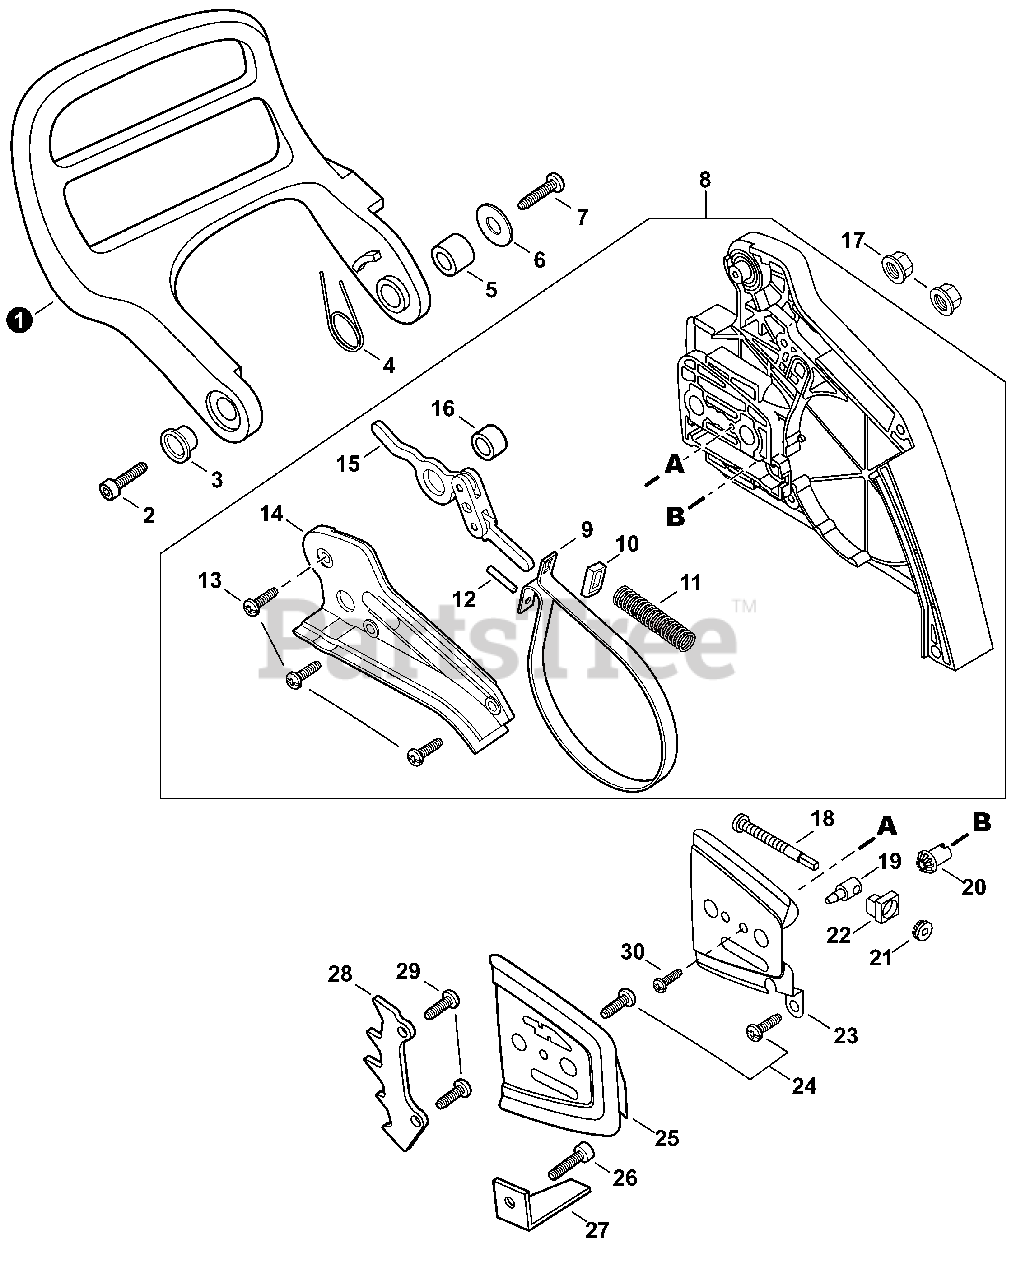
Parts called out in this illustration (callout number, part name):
1	LEVER, BRAKE
2	BOLT 5×16
3	COLLAR 10
4	SPRING, TORSION
5	SPACER 8×12×9
6	WASHER 4.2×16.5×1
8	BRAKE ASSY, CHAIN
9	BAND, BRAKE
11	SPRING, COMPRESSION
12	PIN, SPRING 3x-9.8
13	SCREW 4×12
14	COVER, BRAKE
15	CONNECTOR, BRAKE
16	SPACER 8×12×9
17	NUT, FLANGE M8×1.25
18	SCREW, CHAIN TENSION
19	TENSIONER, CHAIN
20	GEAR, BEVEL
21	GEAR, BEVEL
22	COLLAR 8
23	PLATE, GUIDE - OUTER
24	SCREW 4×12
25	PLATE, GUIDE - INNER
26	BOLT 5×16
27	CHAIN CATCHER
28	SPIKE, BUMPER
29	BOLT 5×20
30	SCREW 3×5
